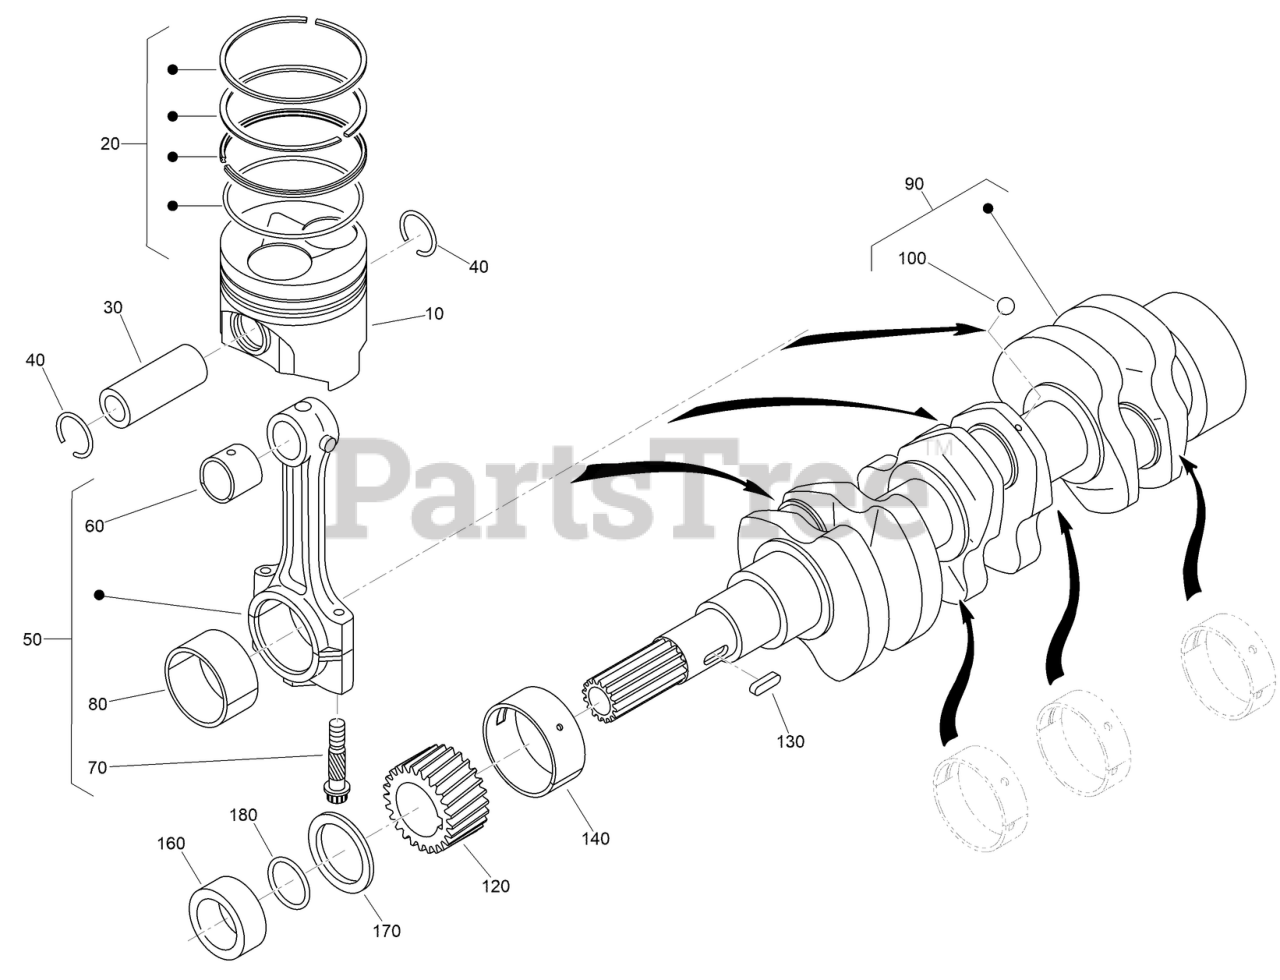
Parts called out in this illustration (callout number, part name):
10	PISTON
20	PISTON RING ASM
30	PIN-PISTON
40	CIRCLIP-INTERNAL
50	CONNECTING ROD ASM
60	BUSHING-PIN, PISTON
70	BOLT-ROD, CONNECTING
80	METAL-CRANKPIN (STD)
80	METAL-CRANKPIN (-.20MM)
80	METAL-CRANKPIN (-.40MM)
90	CRANKSHAFT
120	GEAR-CRANKSHAFT
130	KEY-FEATHER
140	METAL-CRANKSHAFT
160	COLLAR-CRANKSHAFT
170	SLINGER-OIL
180	O-RING
